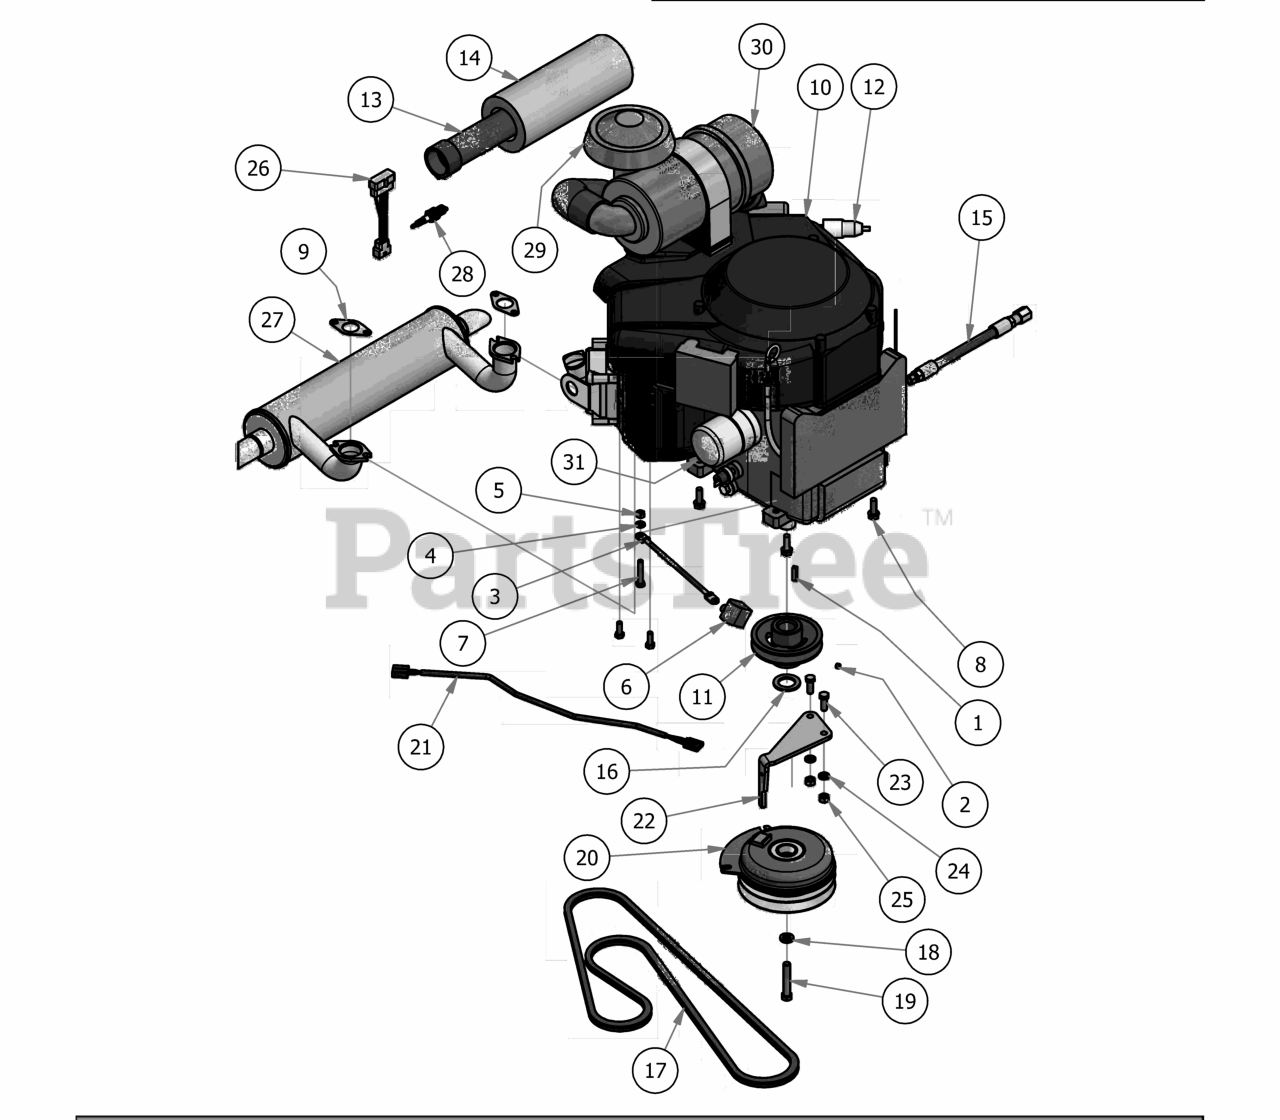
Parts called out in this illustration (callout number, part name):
1	1/4" x 1" Key
2	5/16 Set Screw
3	Ground Cable
4	5/16" Lock Washer
6	Black Boot For Ground Cable
7	5/16" x 1 3/4" Hex Bolt
8	3/8 x 1 1/8 bolt
9	Exhaust Gasket for 23 Vanguard
10	993cc Briggs Vanguard Engine
11	4 3/4 Motor Pulley
12	Universal Inline Fuel Filter
13	Canister Air Filter- Inner
14	Canister Air Filter- Outer
15	14 mm Oil drain Hose 993cc Vanguard
16	1 1/8" Flat Spacer
18	7/16" Lock Washer
19	7/16" x 2 1/2" Hex Bolt
20	Clutch Assembly
21	Clutch Pigtail
22	PTO Engager Holder
23	3/8" x 1" Hex Bolt
24	3/8" Lock Washer
25	3/8" Hex Nut
26	Harness Adaptor - 933cc Vanguard
27	2015 Exhaust - 36hp Vanguard
28	Spark Plug
29	Rain Cap Fits all Canisters
30	Complete Canister
31	Briggs Oil Filter
